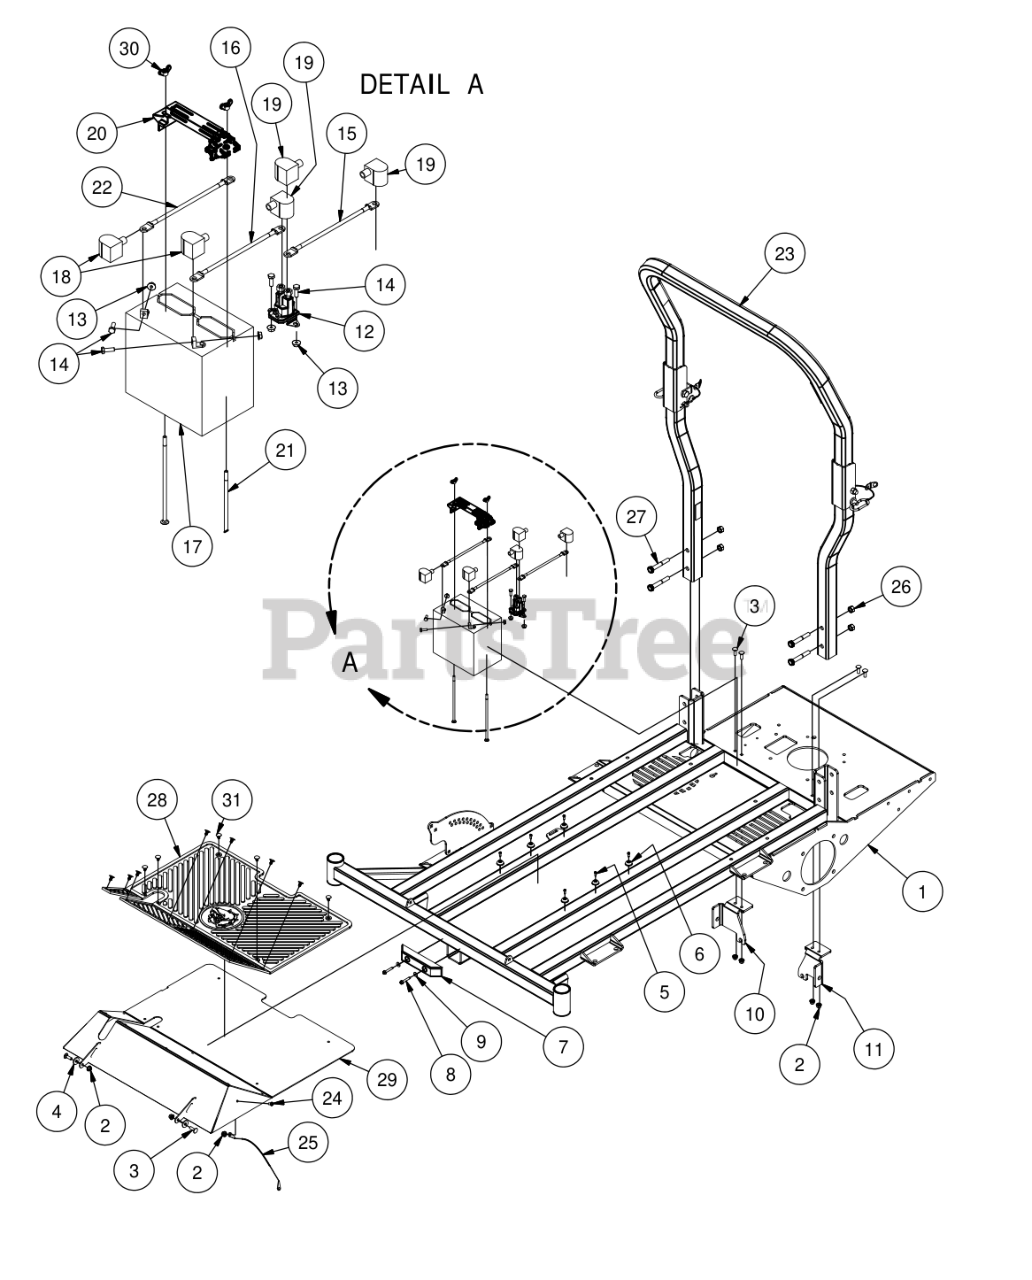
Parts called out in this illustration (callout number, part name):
1	2015 Standard/Extreme Outlaw Frame
2	5/16" Nylock Flange Nut Zinc
3	5/16" x 1" Carriage Bolt
4	.360 ID Plastic Washer
5	#10 x 1/2" Self Tapping Screw
6	Button Bumper
7	8" Rubber Bumper
8	1/4" x 1 1/2" Self Tapping Screw
9	1/4" Flat Washer
10	Outlaw Brake Cable Mount Bracket (Right)
11	Outlaw Brake Cable Mounting Bracket (left)
13	1/4-20 Hex Flange Nuts Zinc w/Serrations
14	1/4-20 x 3/4 GR 5 Hex Bolts Zinc
15	Red Battery Cable Alternator to Starter Cable
16	12 in red battery cable
18	Black Boot For Ground Cable
20	Battery Hold Down
21	1/4-20 X 8 Carriage Bolt
22	Ground Cable
23	2015 Outlaw 2x2 Folding ROPS
24	1/4" x 5/8" BS C/S 18-8 SS
25	Floor board Cable W/ Swivel Ends
26	1/2" Center Lock Nut
27	1/2-13 X 3.25 Hex Bolt - Grade 5
28	2016 Outlaw Floor Mat
29	2016 Outlaw Floor Panel
30	1/4" Wing Nut
31	5/8" Christmas Tree Fastener
